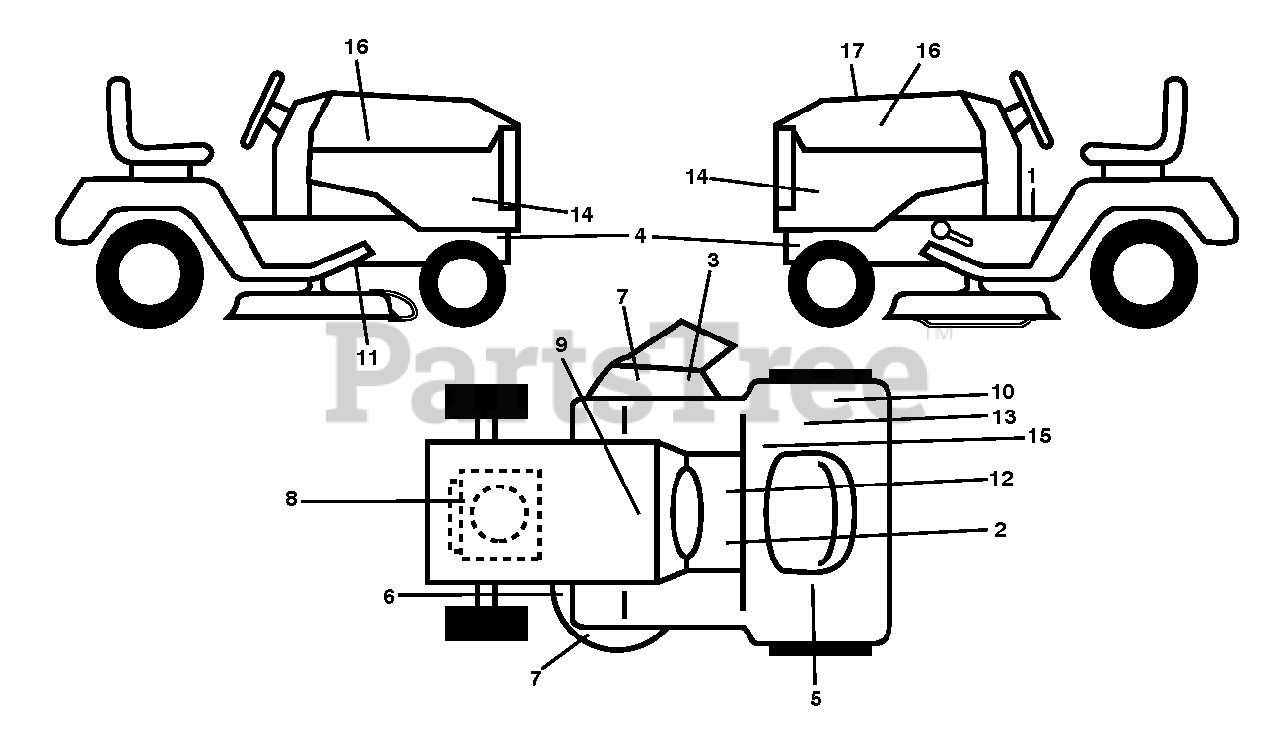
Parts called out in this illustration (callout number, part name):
1	DECAL.RESERVEFUELSELCTR.ENG
2	DECAL.FWD/REV.PEDAL.SYMBOL
3	DECAL, DECK DEFLECTOR, WARNING
4	DECAL.CHASSIS.HOT.MUFFLER
5	DECAL.PARKING.BRAKE.SADDLE.LT
6	DECAL.MOWER.SCH.48/54.PREM
7	DECAL.DECK.6MIL.EURO.NOSTEP
8	DECAL.ENGINE.WARNING
9	DECAL BTRY SYMBOLS
10	DECAL.TICKMARK.6MIL.AUSTRALIA
11	DECAL.PEDAL.HUSQ.CROWN
12	DECAL.READ.OWN.MAN.SYMBOL.LT
13	DECAL.80.DBA.AUSTRALIA
14	DECAL.SDPNL.TS352.SET
15	DECAL.FNDR.SDLE.BRAKE.CLUTCH.6
16	DECAL.BADGE.170MM.TEXTLOGO.
17	DECAL.RPL.KAW.FR730.TGB.52F.G7
